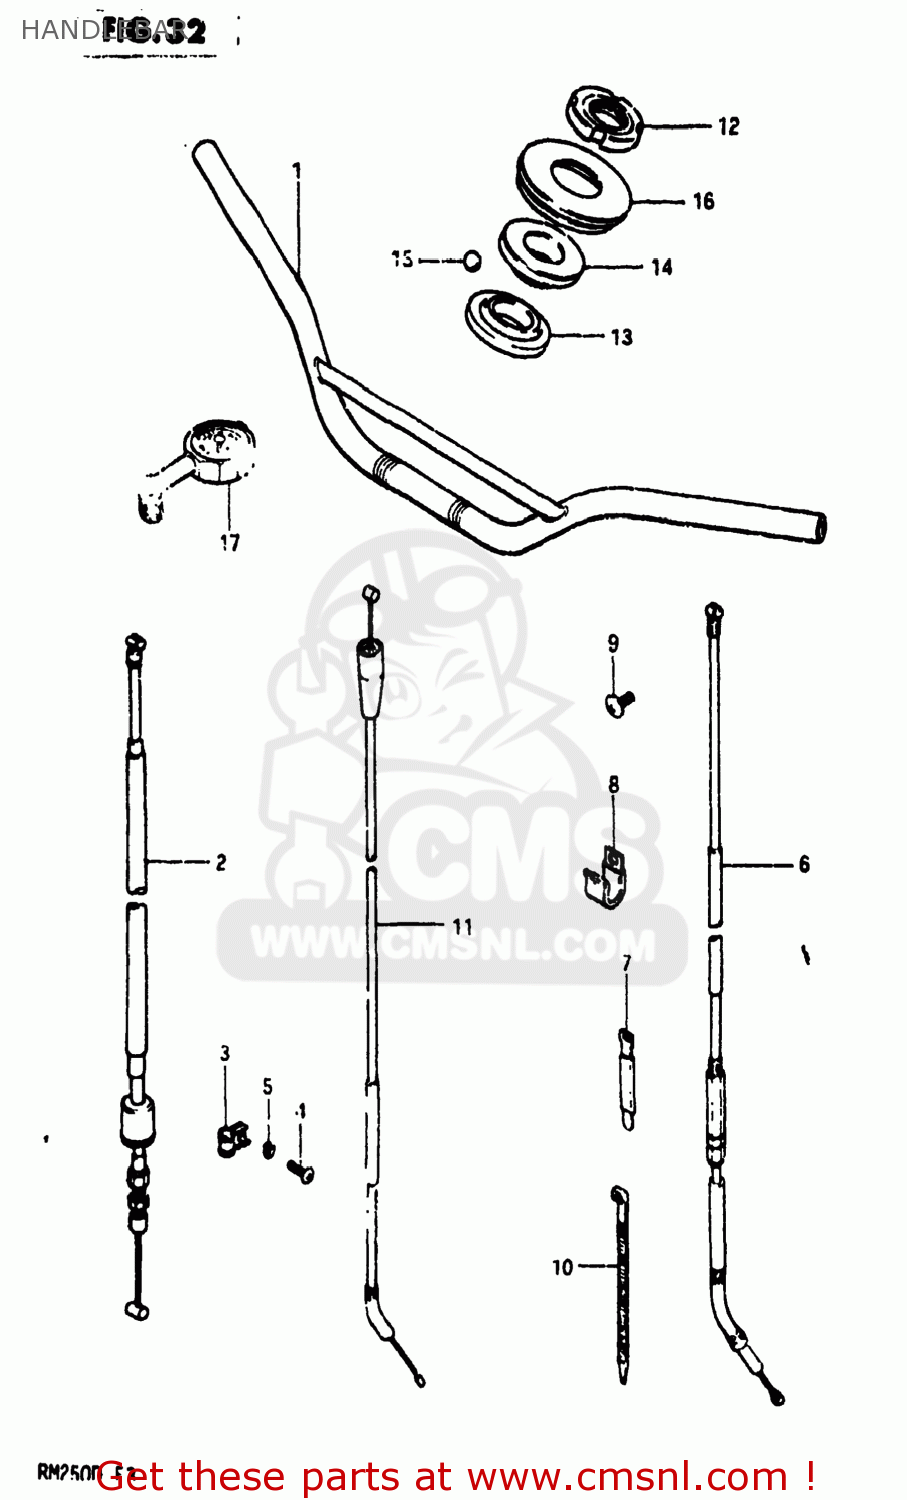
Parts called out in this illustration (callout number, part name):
1	HANDLEBAR
2	CABLE ASSY,FR BRAKE
3	GUIDE,CABLE
4	SCREW
5	LOCK WASHER
6	CABLE ASSY,CLUTCH
7	CLAMP
8	CLAMP
9	SCREW
10	CLAMP
11	CABLE ASSEMBLY,THROTTLE
12	NUT,STEERING STEM
13	RACE,STEERING,INNER,UPPER
14	RACE,STEERING,OUTER,UPPER
15	BALL
16	SEAL,STEERING UPR DUST
17	GAUGE ASSY,AIR PRESSURE
